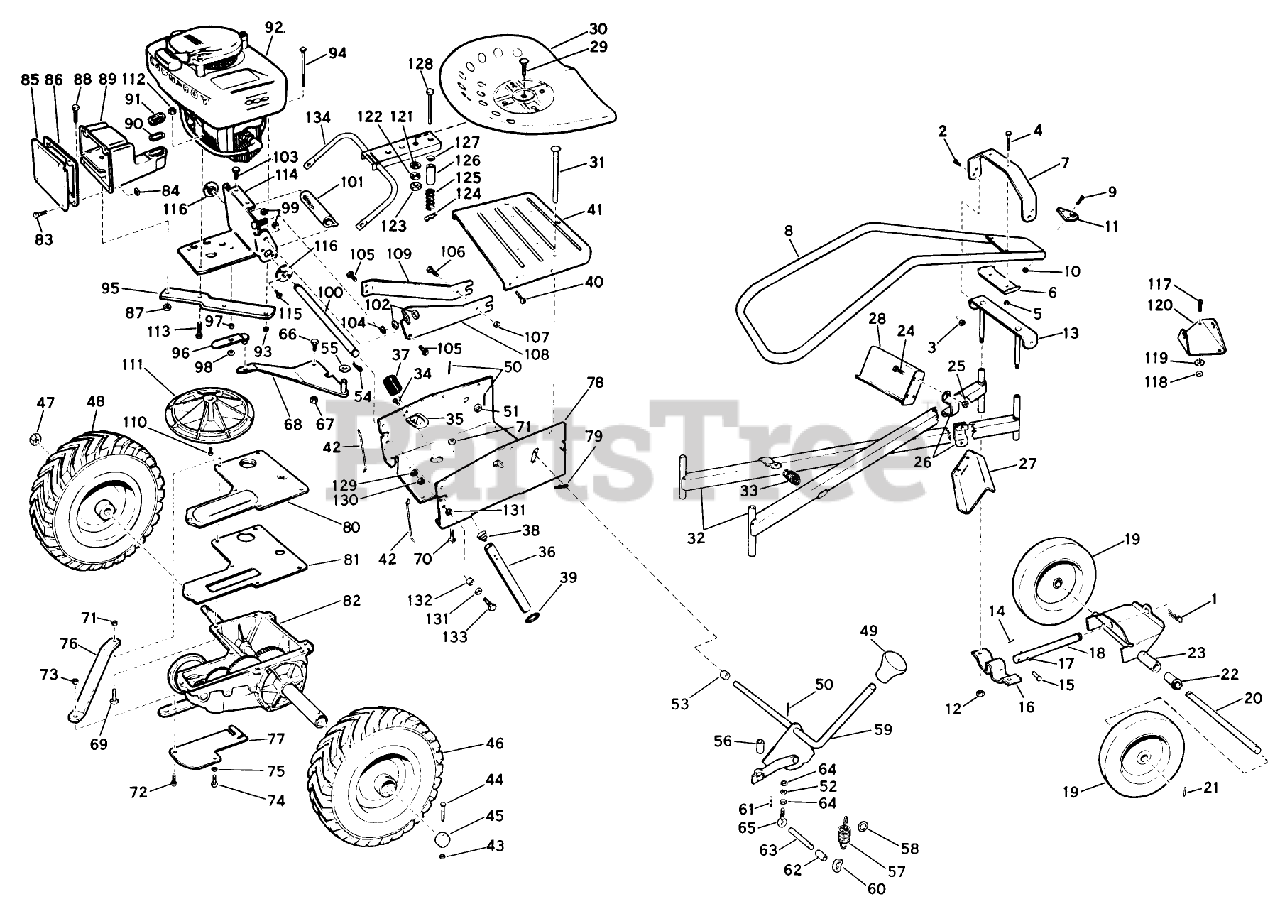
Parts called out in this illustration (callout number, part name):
2	Bolt-Handle
3	STOP NUT
10	STOP NUT
14	Cotter Pin
16	Pivot Bracket-Frame, Bottom
22	Bearing-Wheel, Nylon
29	Carriage Bolt-Seat to Cover
30	Seat Assembly
33	Spring-Clutch
39	Seal, Tube-Oil Filler
41	Cover-Shroud
44	Screw-Differential
52	WASHER, LOCK
53	Roller-Speed Control
54	Spring-Level-Ride Arm
57	Spring-Clutch
65	Bolt-Eye, Ramp Pin Adjustment
69	Screw-Shroud
74	Screw-Guard to Housing
78	Shroud-Frame
87	Nut-Huglok
93	LOCKNUT E
100	Shaft-Engine Mounting Plate
104	WASHER, LOCK
107	STOP NUT
108	Arm-Clutch
116	Bearing-Engine Mounting
118	STOP NUT
125	Spring-Seat
126	Seat Snubber
128	Pin-Spring Guide
134	Seat Support Assembly
